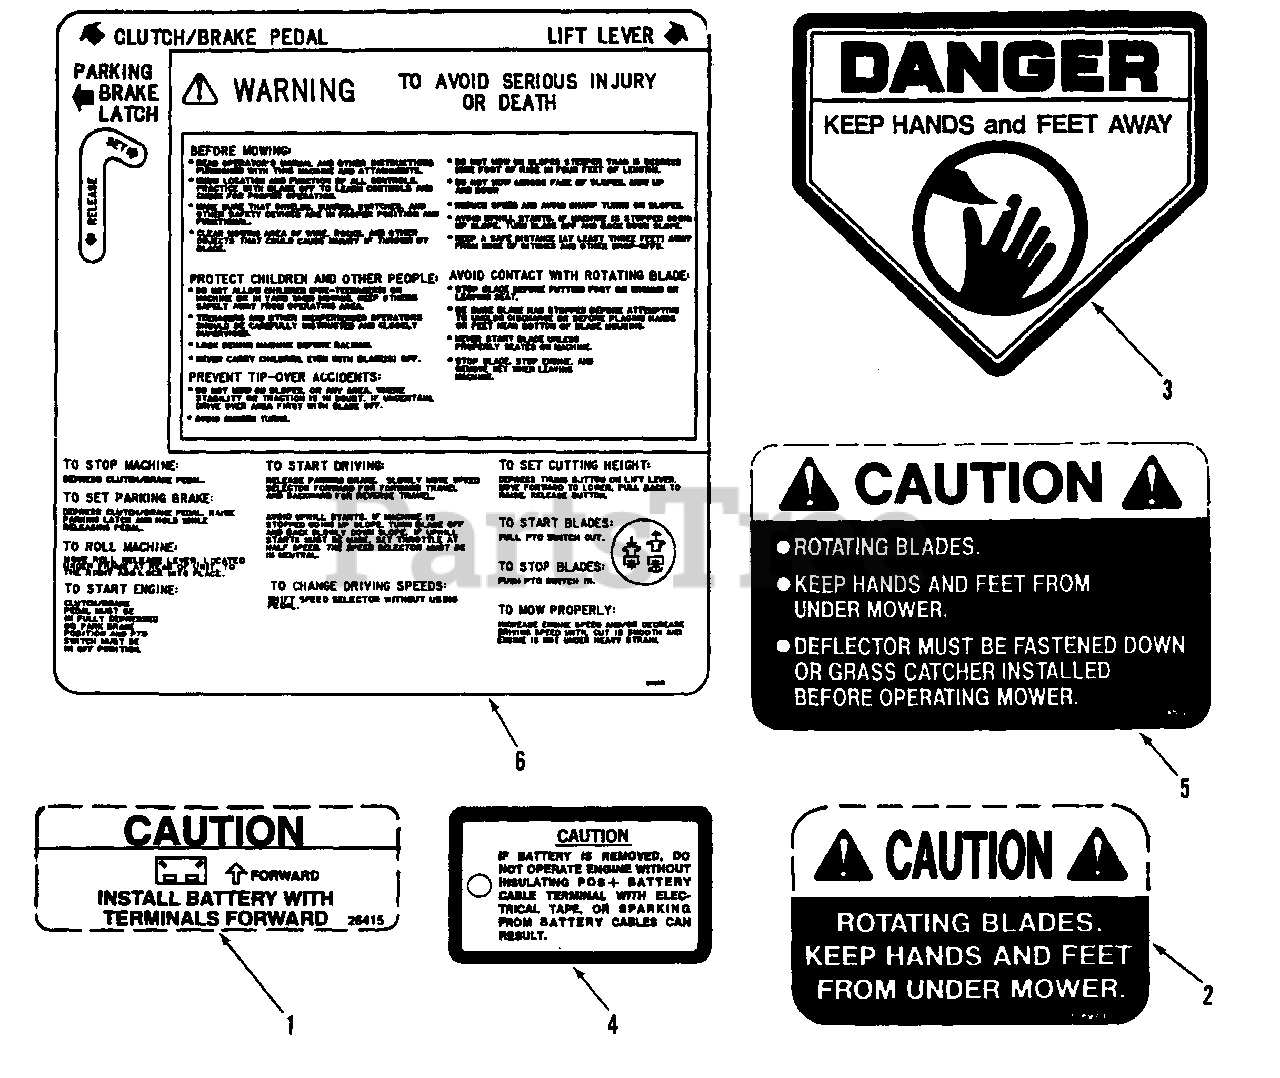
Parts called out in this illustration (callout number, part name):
1	DECAL, Caution
2	DECAL, Caution
3	DECAL, Danger
4	TAG, Caution
5	DECAL, Caution
6	DECAL, Instruction
